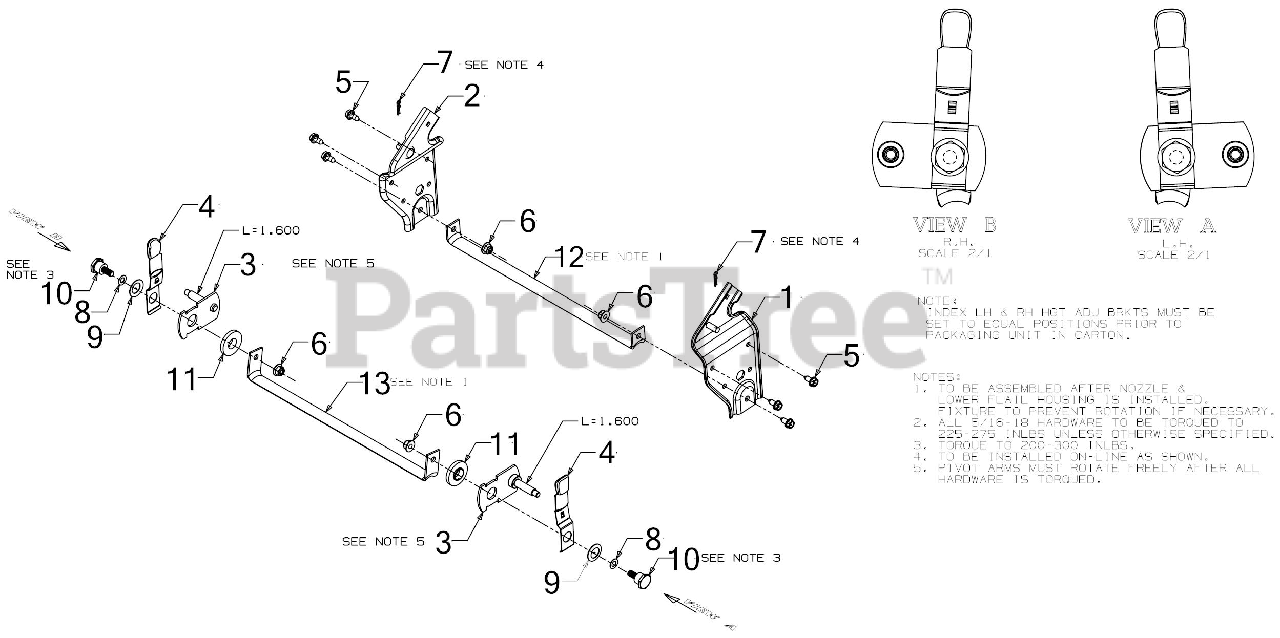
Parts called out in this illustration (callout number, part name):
3	PIVOT ARM ASSEMBLY
4	HEIGHT LEVER ASSEMBLY
5	SCREW 5/16-12 x .750
7	COTTER PIN .072 DIA
8	WASHER THRUST .375X.70X.030
9	BELL WASHER
10	SHOULDER SCREW .75 X.50 X3/8-16
11	HEIGHT ADJUSTMENT BEARING
12	SUPPORT BRACE
13	SUPPORT BRACE
